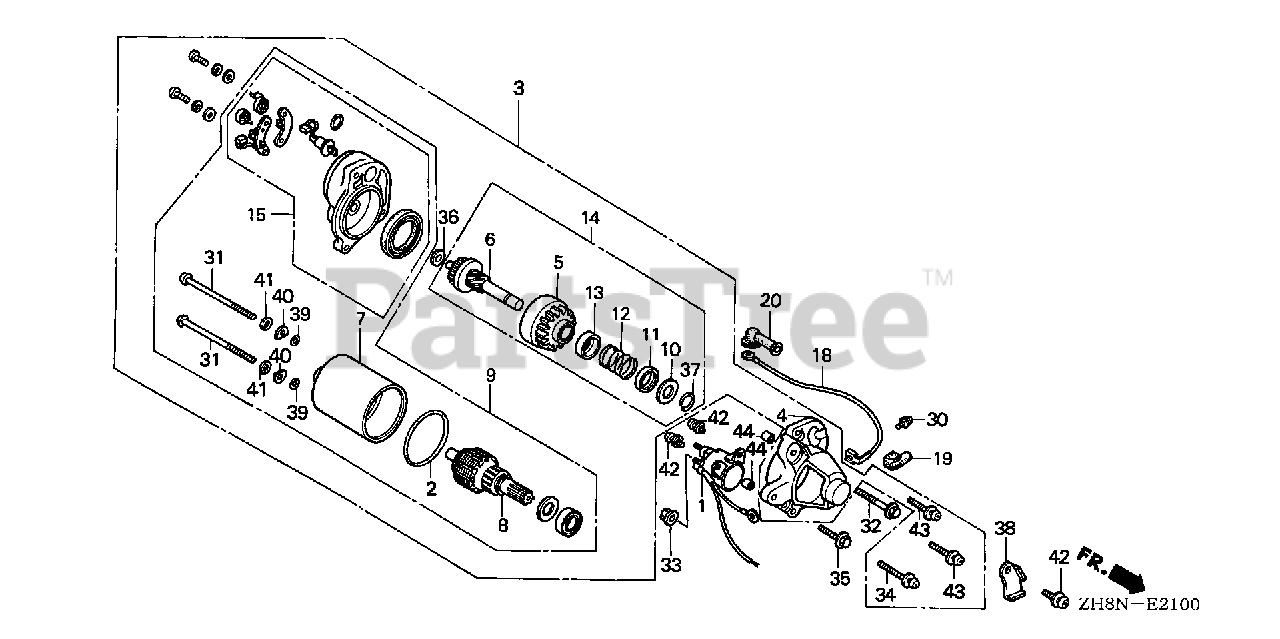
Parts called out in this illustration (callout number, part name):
1	SWITCH, MAGNETIC
2	O-RING
3	MOTOR UNIT, STARTER
4	COVER, GEAR
5	PINION ASSY.
6	SHAFT UNIT, GEAR
7	YOKE ASSY.
8	ROTOR ASSY.
9	MOTOR ONLY
10	PIECE A, STOPPER
11	PIECE B, STOPPER
12	SPRING, RETURN
13	COVER, SPRING
14	GEAR ASSY.
15	BRACKET, FR.
18	WIRE, MAGNET SWITCH
19	COVER, MAGNET SWITCH TERMINAL
20	COVER, STARTER MOTOR TERMINAL
30	SCREW-WASHER (5X8)
31	BOLT, SETTING
32	BOLT, FLANGE (6X32)
33	NUT-WASHER (6MM)
34	SCREW-WASHER (5X30)
35	BOLT, FLANGE (6X25)
36	WASHER, PINION
37	CIRCLIP (10.2MM)
38	HOLDER, HARNESS
39	O-RING
40	WASHER, SPECIAL
41	WASHER, SPRING
42	SCREW-WASHER (5X14)
43	SCREW-WASHER (5X20)
44	PIN A, DOWEL (8X10)
